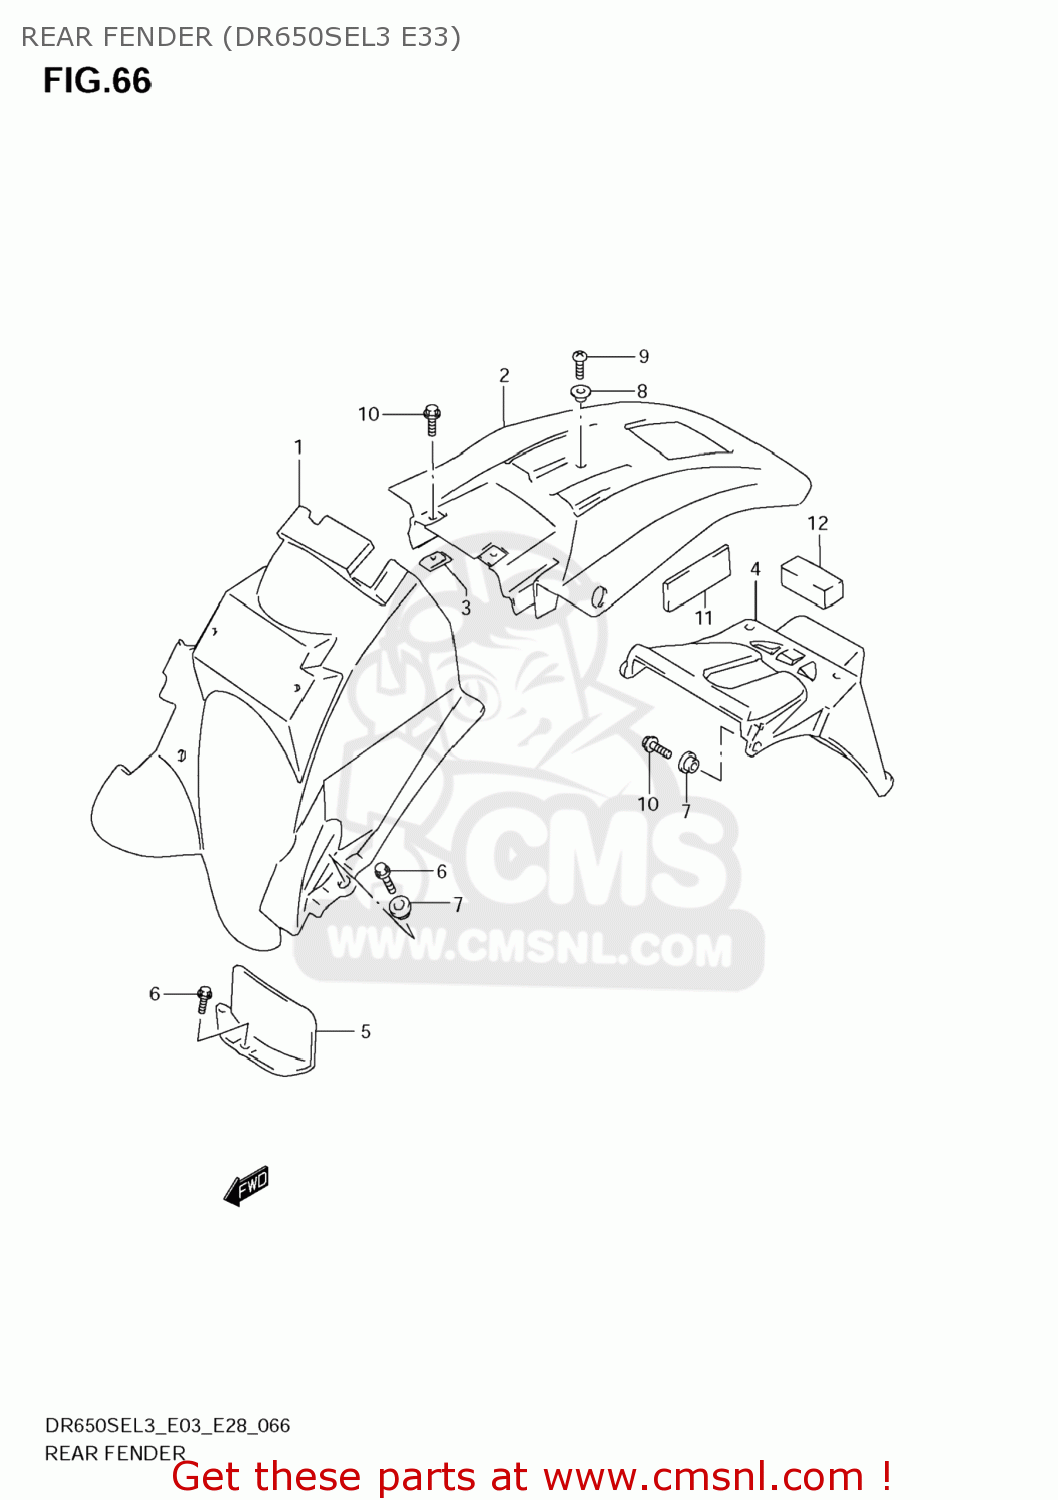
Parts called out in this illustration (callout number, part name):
1	BODY,RR FENDER FR
2	BODY,RR FENDER
3	PLATE,FRAME COVER
4	EXTENSION,RR FENDER
5	MUDGUARD,RR FENDER
6	BOLT(6X16)
7	WASHER
8	WASHER
9	SCREW(6X16)
10	BOLT
11	CUSHION,RR FENDER
12	CUSHION
